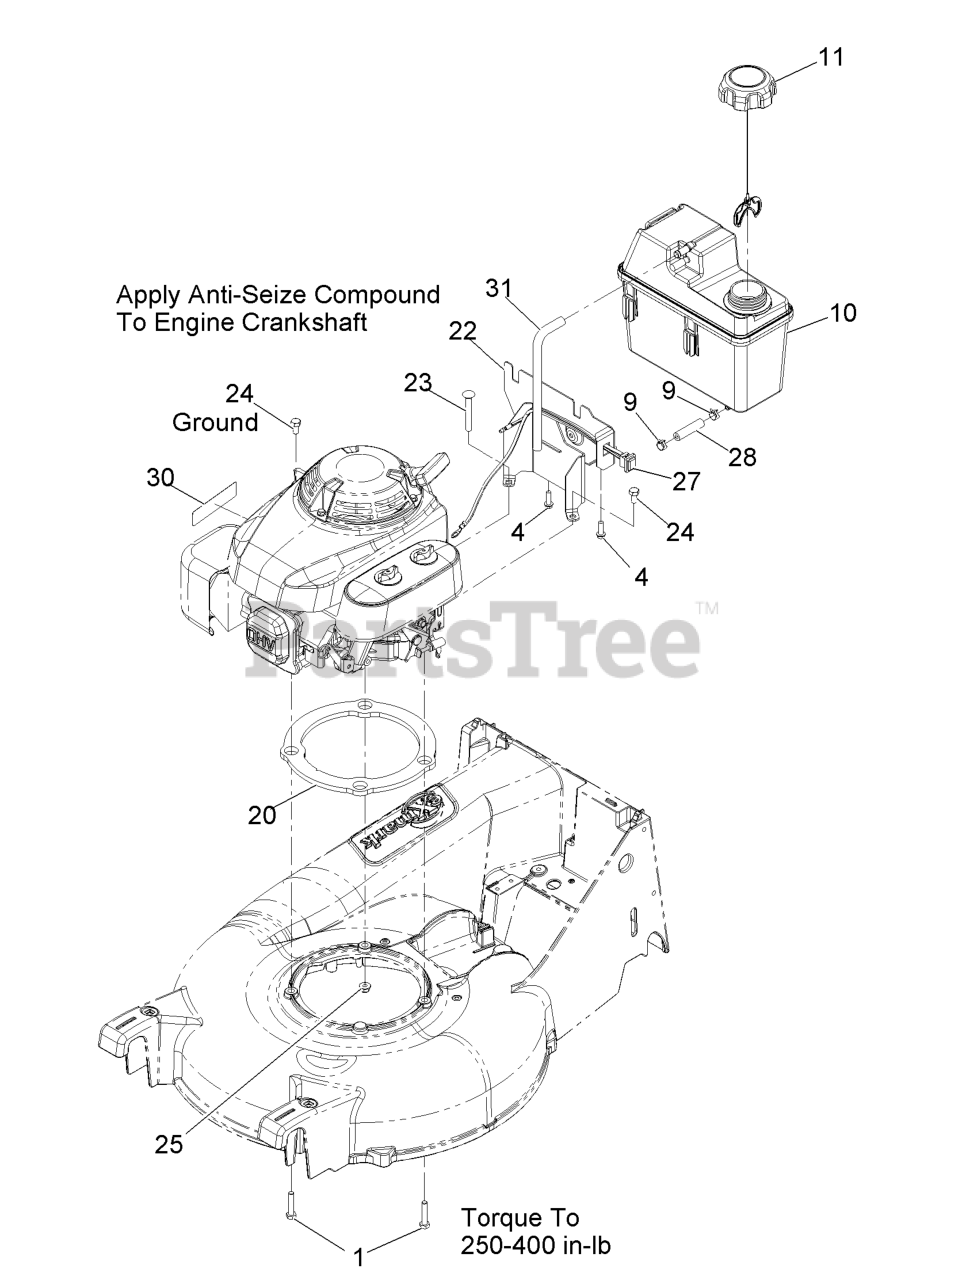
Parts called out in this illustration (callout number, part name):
1	SCREW-HH
4	SCREW-HWH
9	CLAMP-HOSE
10	TANK-FUEL
20	GASKET,DECK
22	BRACKET ASM
23	SCREW-CARR
24	SCREW-HH
25	NUT-HF, NI
27	HARNESS,RUN/STOP
28	HOSE-FUEL
30	DECAL-ARRESTER, SPARK
31	HOSE-VENT, CANISTER
